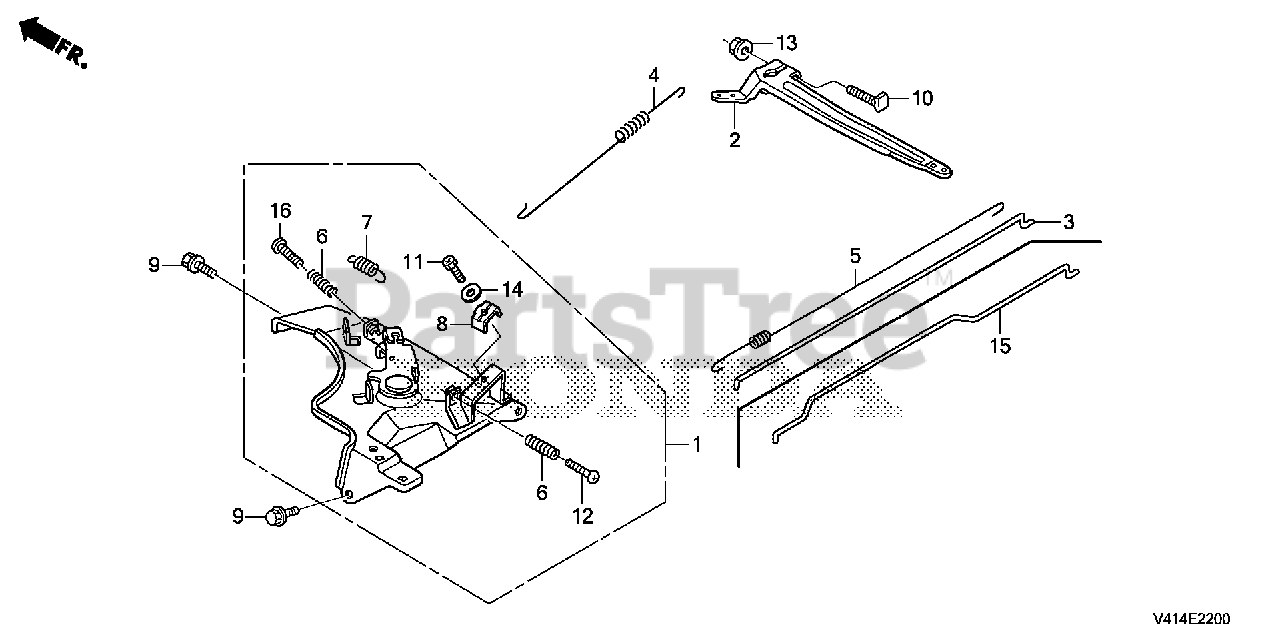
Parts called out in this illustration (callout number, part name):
1	CONTROL ASSY.
1	CONTROL ASSY. (COO)
2	ARM, GOVERNOR
3	ROD, GOVERNOR
4	SPRING, GOVERNOR (L=137.5MM)
5	SPRING, THROTTLE RETURN
6	SPRING, CONTROL ADJUSTING
7	SPRING, CONTROL LEVER RETURN
8	HOLDER, CABLE
9	BOLT, FLANGE (6X12) (CT200)
10	BOLT, GOVERNOR ARM
11	BOLT, RECESSED (5X22)
12	SCREW, PAN (5X32)
13	NUT, FLANGE (6MM)
14	WASHER, PLAIN (5MM)
16	SCREW, PAN (5X32)
